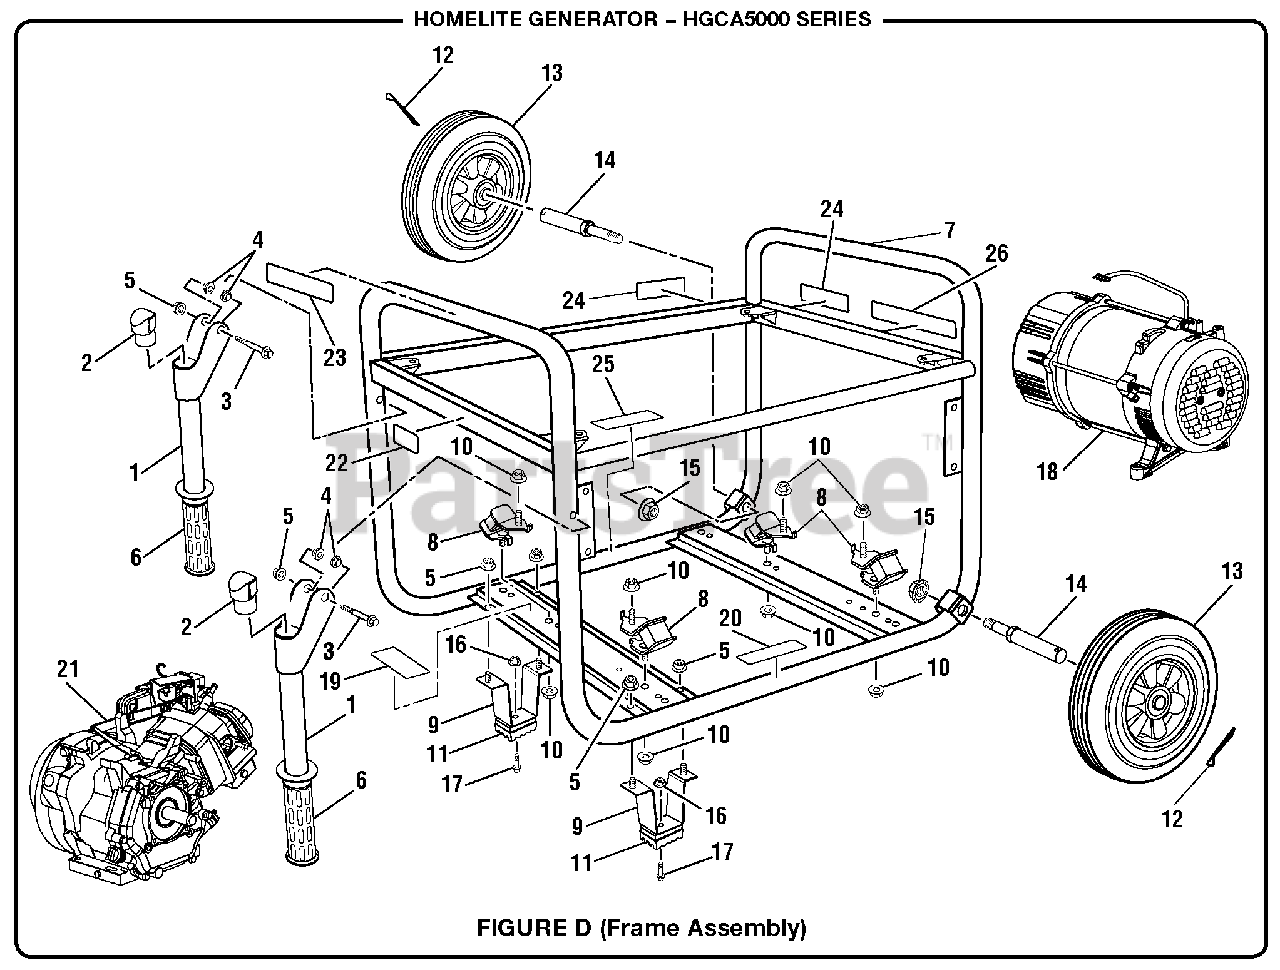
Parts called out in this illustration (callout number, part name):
1	Handle Bar Assembly (Incl. Key No. 6)
2	Handle Bar Plug
3	Bolt (M8 x 45 mm)
4	Handle Bar Insert
6	Handle Grip
8	Motor Mount
9	Foot Bracket
10	Nut (M10)
11	Rubber Foot
12	Cotter Pin (3 mm)
13	Wheel (10 in.)
15	Nut (M12, Flange Hd.)
16	Flange Nut (M6)
17	Screw (M6 x 25)
18	Generator Head Assembly (Incl. Key Nos. 1-10)
19	Data Label
20	Lubricant Label
21	Engine 420cc
22	Fuel Valve Label
23	Fire Danger Label
24	Hot Surface Warning Label
25	Combustion Label
26	Ground Warning Label
